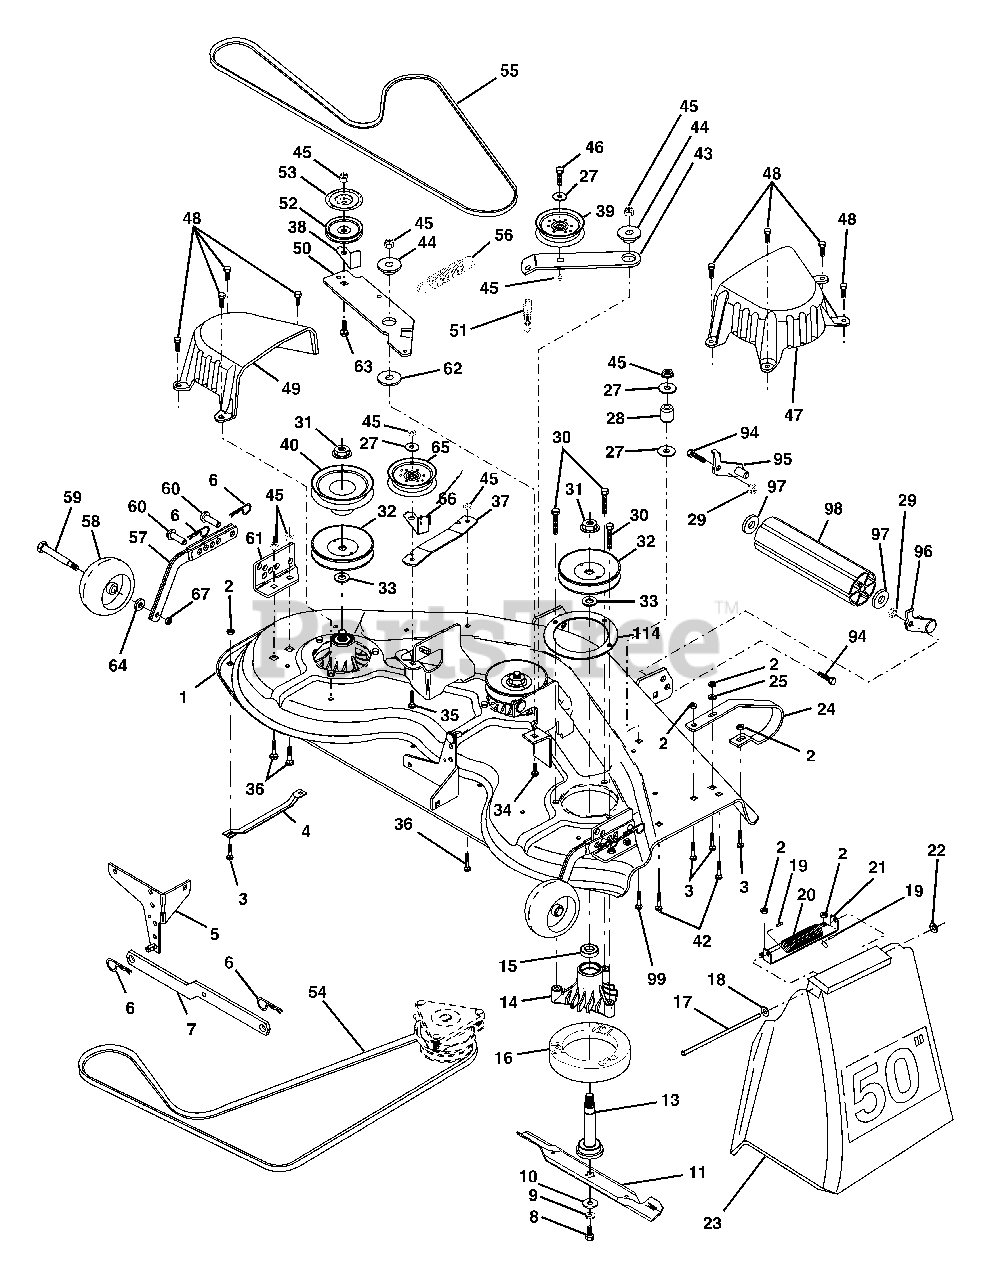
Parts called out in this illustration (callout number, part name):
1	Deck Asm., Mower 50"
2	Nut, Crownlock 5/16-18
3	Bolt Rd Hd Sqnk 5/16-18 Unc x 3/4
4	Runner LH
5	Bracket Asm., Sway Bar
6	Retainer, Spring
7	Bar Sway Deck
8	Bolt 3/8-24 x 1.25 Gr. 8 Patched
9	Washer, Lock Hvy 3/8 Unplated
10	Washer, Hard Blade Mower Vented
11	Blade (3 Required)
13	Shaft Asm., W/Lower Brg
14	Housing, Mandrel 50" Vent
15	Bearing, Ball Mandrel
16	Stripper, Mower Vented
17	Rod, Hinge
18	Washer 11/32 x 5/8 x 16 Ga.
19	Cap Sleeve
20	Spring, Torison Delector
21	Bracket, Deflector
23	Shield, Deflector Mower
25	Washer 11/32 x 3/4 x 16 Ga.
26	Bolt Rd Hd Sht Sqnk
27	Washer 13/32 x 13/16 x 16 Ga.
28	Spacer, Spring Stop Idler
29	Nut, Lock 5/16-18
30	Screw Thd Rolling
31	Nut, Flg Top Lock Cntr 9/16
32	Pulley, Mandrel, Plated
33	Washer, Spacer Mower Vented
34	Bolt, Carriage 3/8-16 x 1-1/4
35	Bolt, Carriage 3/8-16 x 2
36	Bolt, Carriage 3/8-16 x 1 Gr. 5
37	Stiffener, Arm Idler
38	Keeper, Belt Idler
39	Pulley, Idler Flat
40	Pulley, Driven
42	Bolt, Carriage 5/16-18 Unc x 3/4
43	Arm, Idler Secondary
44	Spacer, Retainer
45	Nut, Crownlock 3/8-16 Unc
46	Bolt, Fin Hex 3/8-16 Unc x 1-3/4
47	Cover, Mandrel RH
48	Screw, Thd Roll 1/4-20 x 5/8
49	Cover, Mandrel LH
50	Arm, Idler Primary
51	Spring, Secondary
52	Pulley, Idler V Groove
53	Shield, Idler
54	V-Belt, Mower Primary
55	V-Belt, Mower Secondary
56	Spring, Primary
57	Bar Asm. Wheel Gauge Mower
58	Wheel, Gauge
59	Bolt, Shoulder
60	Pin Clevis
61	Bracket Gauge Wheel
62	Washer Hardened
63	Bolt Carriage 3/8-16 x 1-1/2
64	Washer 3/8 x 7/8 x 14 Ga.
65	Pulley Idler Flat Mower
66	Keeper, Belt Idler Plated
67	Nut, Center Lock 3/8-16
94	Bolt H 5/16-18 x 1
95	Bracket, Asm. Noseroller LH
96	Bracket, Asm. Noseroller RH
97	Washer 17/32 x 7/8 x 16 Ga.
98	Roller, Nose
99	Bolt, Carriage 3/8-16 x 1-3/4 Gr. 5
114	Reinforcement Mandrel Ring
114	Mandrel Asm
